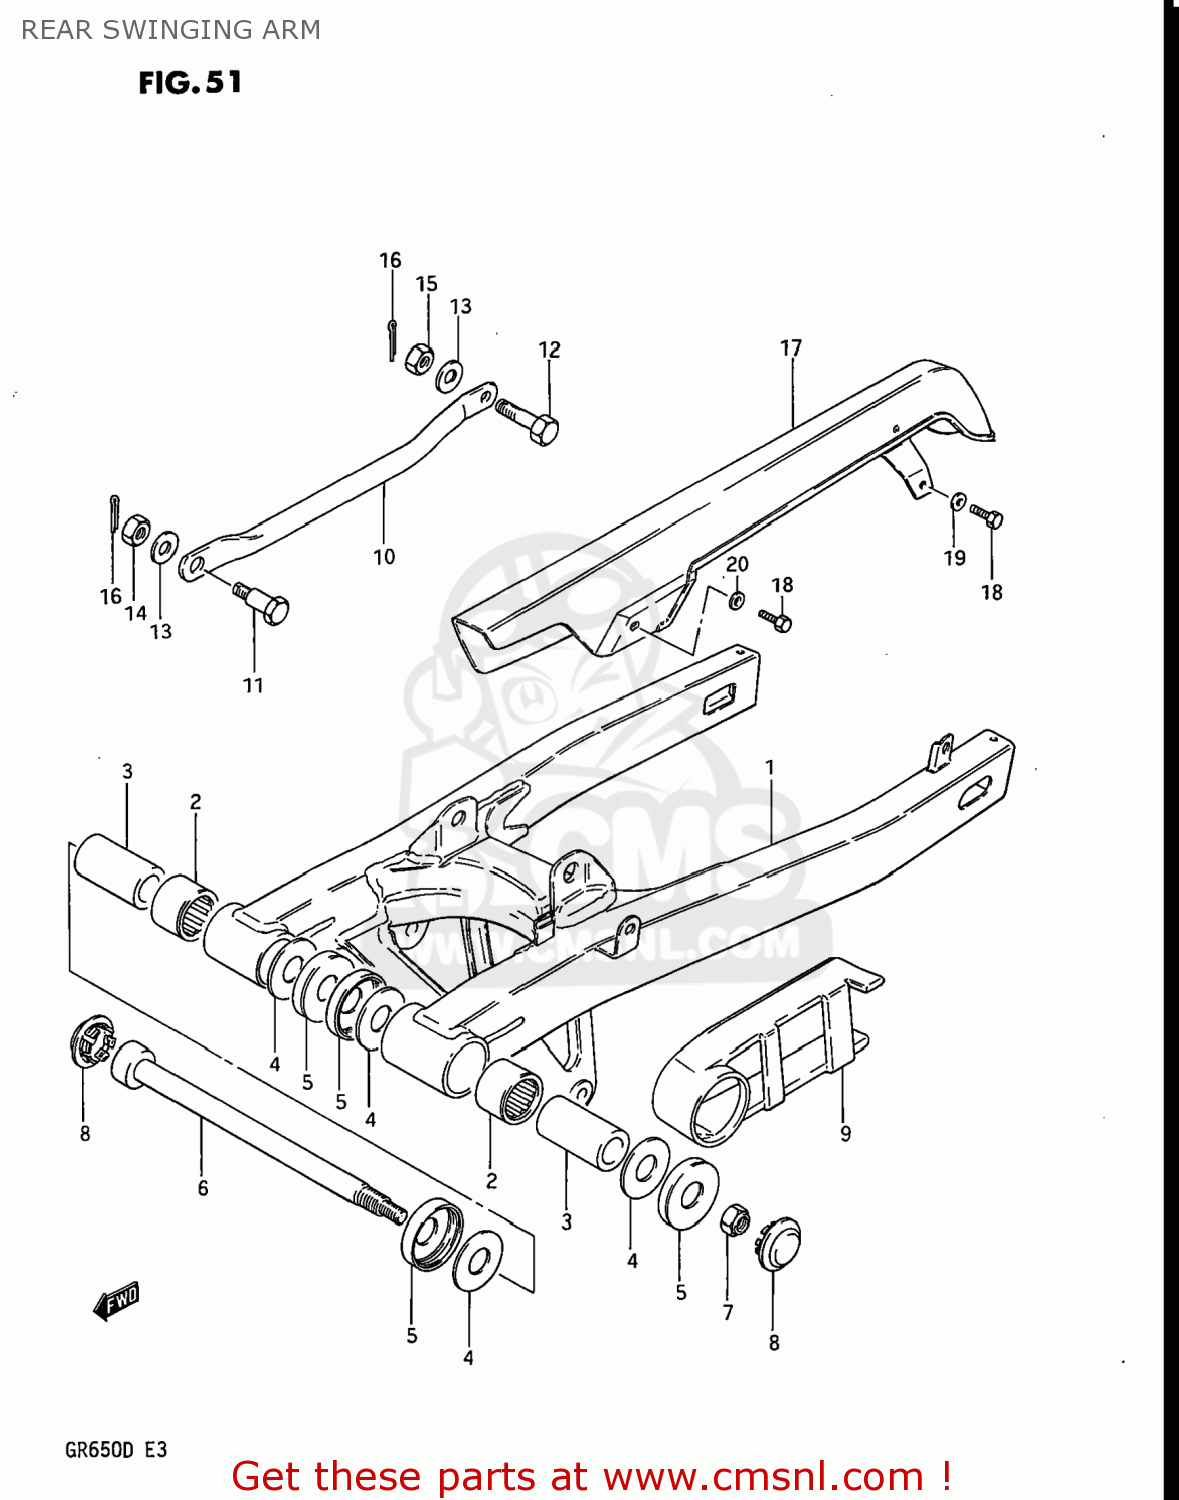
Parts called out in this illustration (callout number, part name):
1	SWING ARM ASSEMBLY,REAR
2	BEARING(25X33X30)
3	SPACER,RR SWGARM PIVOT
4	WASHER
5	COVER,RR SWGARM DUST SEAL
6	SHAFT,REAR SWING ARM
7	NUT 12MM
8	CAP,REAR SWING ARM PIVOT
9	BUFFER,DEFENSE
10	LINK,REAR TORQUE
11	BOLT(10X24.5)
12	BOLT(10X31)
13	LOCK WASHER
14	NUT
15	NUT
16	PIN 20X20
17	CASE,CHAIN
18	BOLT 6X8
19	WASHER
20	WASHER
